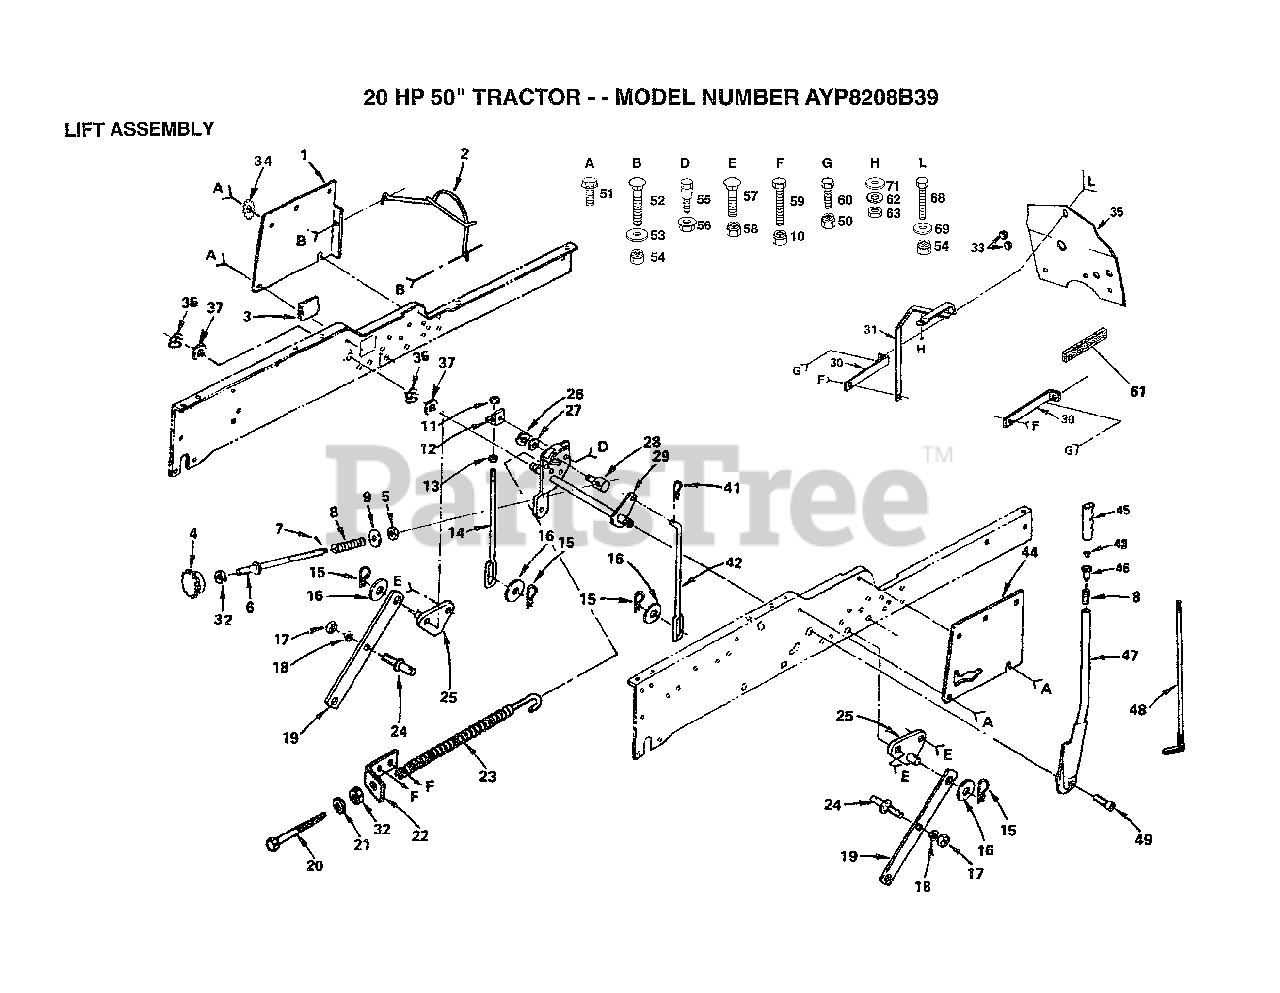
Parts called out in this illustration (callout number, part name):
2	"GUARD, BELT"
3	COVER ACCESS
4	KNOB INF 3/8-16
5	NUT T
6	ROD ADJ. T
8	SPRING T
9	WASHER
11	NUT
12	BRACKET T
13	NUT.HEX.3/8-16UNC
14	LINK-LIFT MOW T
15	SPRING H
17	NUT
18	LOCKWASHER
19	SUSPENSION ARM GT
20	BOLT-ADJ SPRING T
21	WASHER
24	PIVOT STUD GT
25	SUSP BRACKET T
26	KLIP RING
27	WASHER
28	TRUNION LT
29	SHAFT ASS'Y LIFT
30	BRACKET T
32	NUT
34	LOCKWASHER
35	"SHIELD HEAT, BASE"
36	E-RING
37	WASHER
42	LIFT LINK RH T
45	GRIP
48	LEVER ROD LT
49	"BOLT,HEX"
51	SCREW LT
52	BOLT
53	WASHER
55	SHOULDER BOLT T
56	NUT T
57	BOLT
58	LOCKNUT
59	BOLT
60	BOLT
61	FOAM STRIP T
68	BOLT
69	WASHER M
71	WASHER PM
